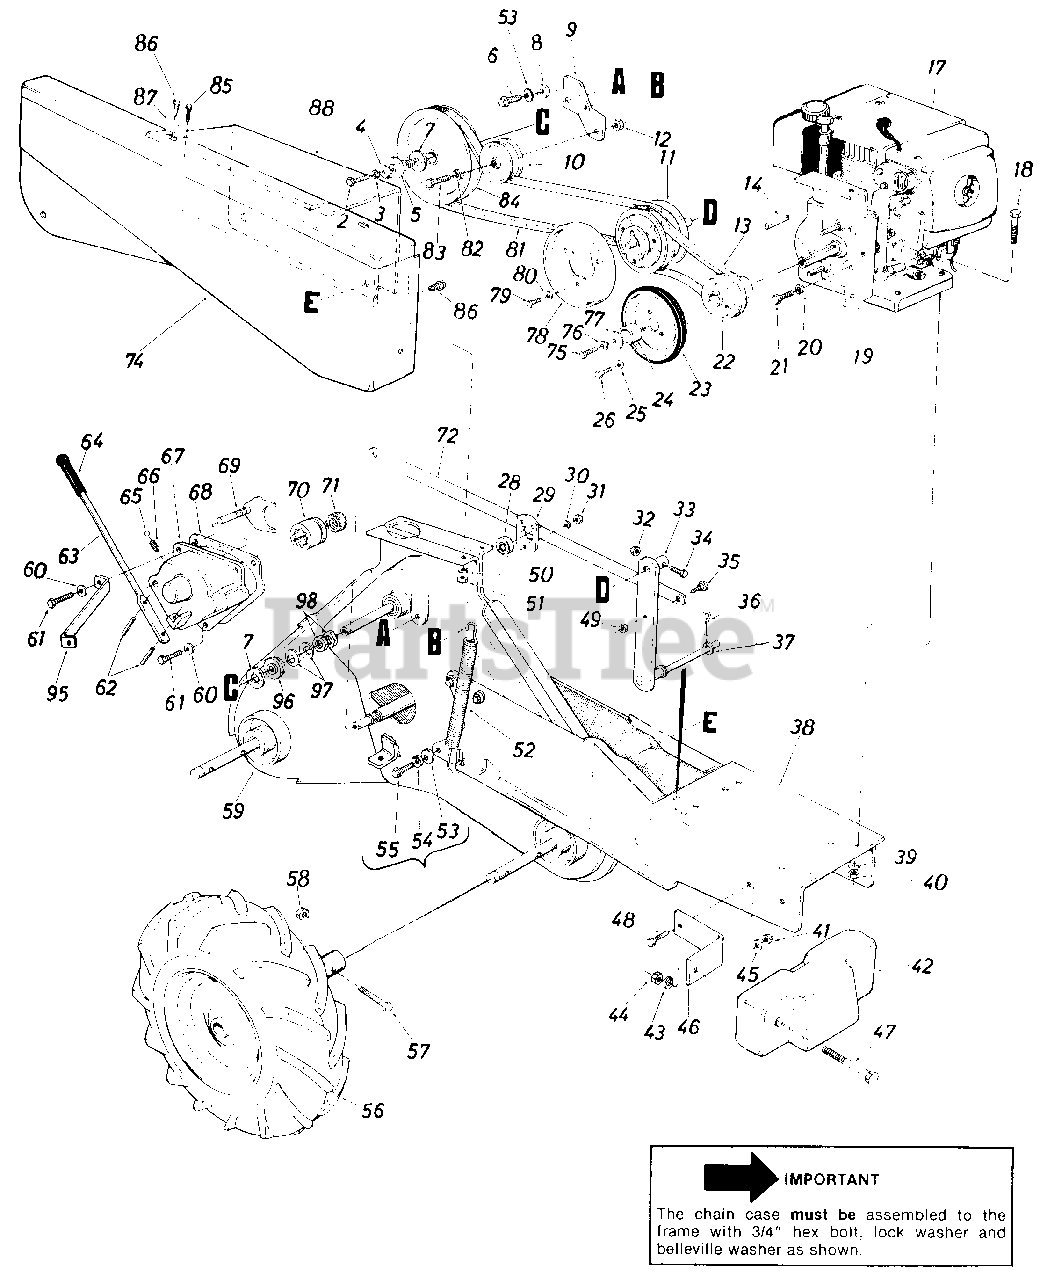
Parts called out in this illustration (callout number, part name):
2	Hex L-Bolt 5/16-24 x 1.5" Lg.
3	L-Wash. 5/16" I.D.
4	Fl-Wash. 5/16" I.D. x 1.125" O.D.
5	Friction Disc Ass'y.
6	Hex Bolt 3/8-24 x 1.25" Lg.
7	Friction Pad
8	Shoulder Spacer
9	Idler Bracket
10	Fl-Idler 2.75" Dia.
11	Variable Speed Ass'y.
12	Hex Ins. L-Nut 3/8-16 Thd.
13	"V"-Belt 5/8" x 27.0" Lg.
14	Sq. Key 1/4" x 2.00" Lg.
17	Engine
18	Hex Bolt 5/16-18 x 1.75" Lg.
19	Belt Cover Support Ass'y.
20	Internal L-Wash. 1/2" I.D.
21	Hex Bolt 1/2-20 x .75" Lg.
22	Engine Pulley Ass'y.
23	Friction Wheel Ass'y.
24	Spacer
25	L-Wash. 5/16" I.D.
26	Hex Bolt 5/16-18 x .50" Lg.
28	Ball Bearing
29	Bearing Housing 1-3/8" O.D.
30	L-Wash. 1/4" I.D.
31	Hex Nut 1/4-28 Thd.
32	Hex Ins. L-Nut 1/4-20 Thd.
33	Variable Speed Brkt. Ass'y.
34	Hex Bolt 1/4-20 x 1.25" Lg.
35	Shld. Bolt 1/2" Dia. x .25" Lg.
36	Cotter Pin 1/8" Dia. x 1.0" Lg.
37	Fl-Wash. .686" I.D. x 1.25" O.D.
38	Frame Ass'y.
39	L-Wash. 5/16" I.D.
40	Hex Nut 5/16-18 Thd.
41	Hex Cent. L-Nut 3/8-24 Thd.
43	Fl-Wash. .50" I.D. x 1.0" O.D.
44	Hex Nut 1/2-13 Thd.
45	L-Wash. 3/8" I.D.
46	Weight Mtg. Brkt.
47	Hex Bolt 1/2-13 x 4.50" Lg.
48	Hex Bolt 3/8-24 x 1.00" Lg.
49	Hex Ins. L-Nut 3/8-16 Thd.
50	L-Wash. 1/4" I.D.
51	Hex Cent. L-Nut 1/4-28 Thd.
52	Spring Idler Bracket
53	Belleville Wash. 3/8" I.D.
54	L-Wash. 3/8" I.D.
55	Hex Self-Tap Scr. 3/8-16 x 5" Lg.
56	Wheel Ass'y. Comp. - R.H.
57	Hex Bolt 3/8-24 x 1.25" Lg.
58	Hex Ins. L-Nut 3/8-24 Thd.
59	Chain Case Ass'y. Comp.
60	L-Wash. 5/16" I.D.
61	Hex Tap Tite Scr. 5/16-18 x .75" Lg
62	Headed Spiral Pin 3/16 x 13/16" Lg.
63	Engagement Lever
65	Ball Detent .250" Dia.
66	Compression Spring
67	Shift Housing - R.H.
68	Gasket - Shift Housing
69	Shift Yoke Ass'y. - R.H.
70	Clutch Dog
71	Clutch Dog Driver
72	Control Brkt.
74	Shroud Belt Cover
75	Hex Bolt 7/16-20 x 2.25" Lg.
76	L-Wash. 7/16" I.D.
77	Fl-Wash. .44 I.D. x 1.38" O.D.
78	Friction Disc
79	Hex Bolt 1/8-28 x .50" Lg.
80	L-Wash. 1/4" I.D.
81	"V"-Belt 5/8" x 51" Lg.
82	L.-Wash. 3/8" I.D.
83	Hex Bolt 3/8" x 1.50" Lg.
84	Input Pulley - Chain Case
85	Hex Bolt 1/4-28 x .62" Lg.
86	Hex Wash. Hd. Self-Tap Scr.
87	Fl-Wash. 1/4 I.D.
88	Belt Cover Shroud
96	Floating Disc
97	Spring Bell-Wash.
98	Hex Jam Nut 1.0-14
